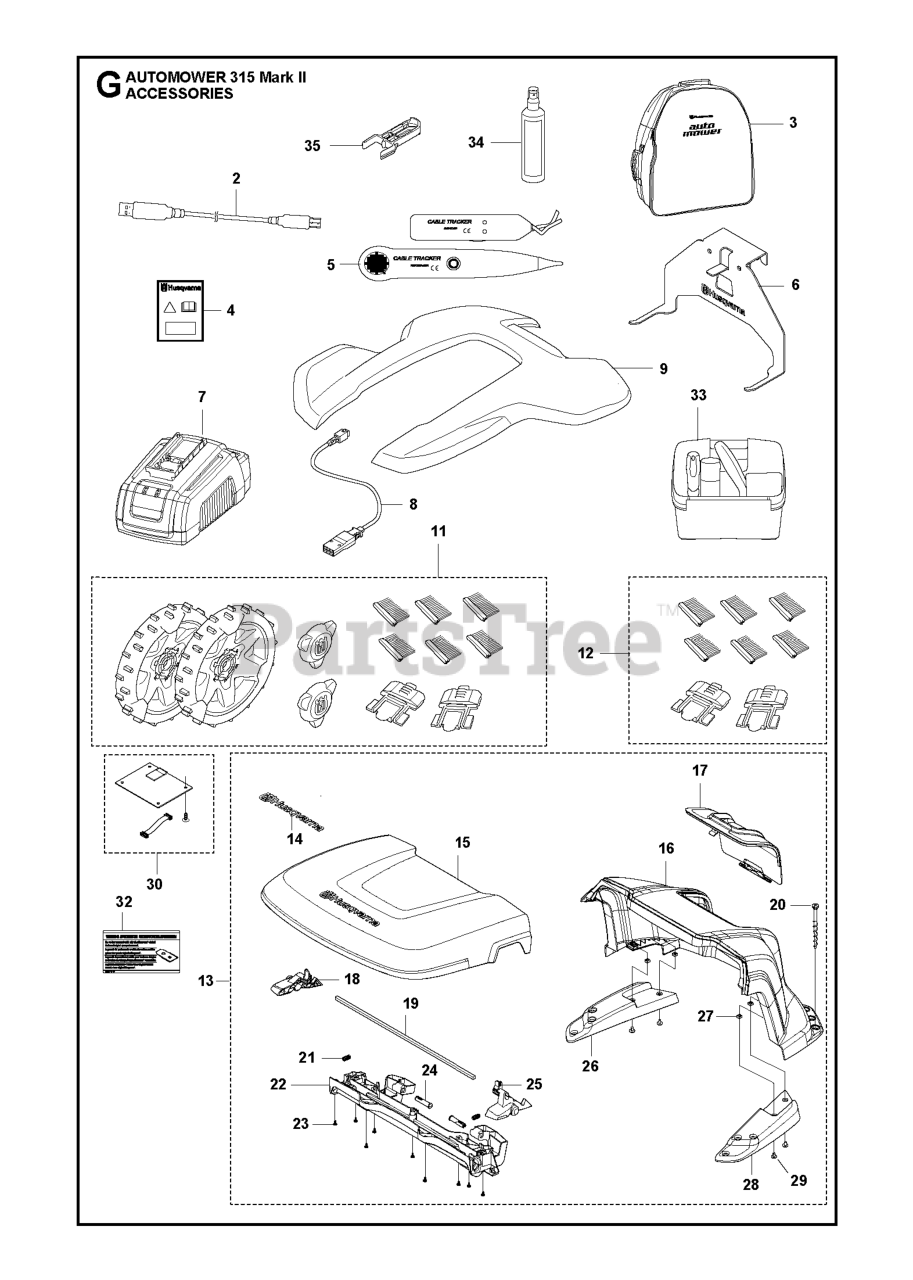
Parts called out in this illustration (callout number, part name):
2	CABLE WHITE ALT GREY
3	BAG
4	LABEL WARRANTY SEAL DEALER
5	TEST EQUIPMENT
7	CHARGER BATTERY TEST
8	CABLE ASSY QUICK CHARGER
12	BRUSH WITH CARTON
13	HOUSE KIT FOR 315
14	DECAL.HUSQVARNA.210MM
15	COVER LID 315
16	COVER BASE P15
17	HATCH
18	HANDLE RELEASE LEFT
19	ROD
20	Screws
21	SPRING SPRING CAP
22	BEAM
23	SCREW 14MM
24	HINGE PIN
25	HANDLE RELEASE RIGHT
26	SUPPORT BASE LEFT
27	NUT
28	SUPPORT BASE RIGHT
29	SCREW IHPANM M6X25 4.6 ZP-BC
30	GPS MODULE 2G + 3G
32	DECAL WARNING ORIGINAL BLADE E
32	ORIGINAL PARTS STICKER
33	CLEANING AND MAITENANCE KIT AM
34	AUTOMOWER ACCY
